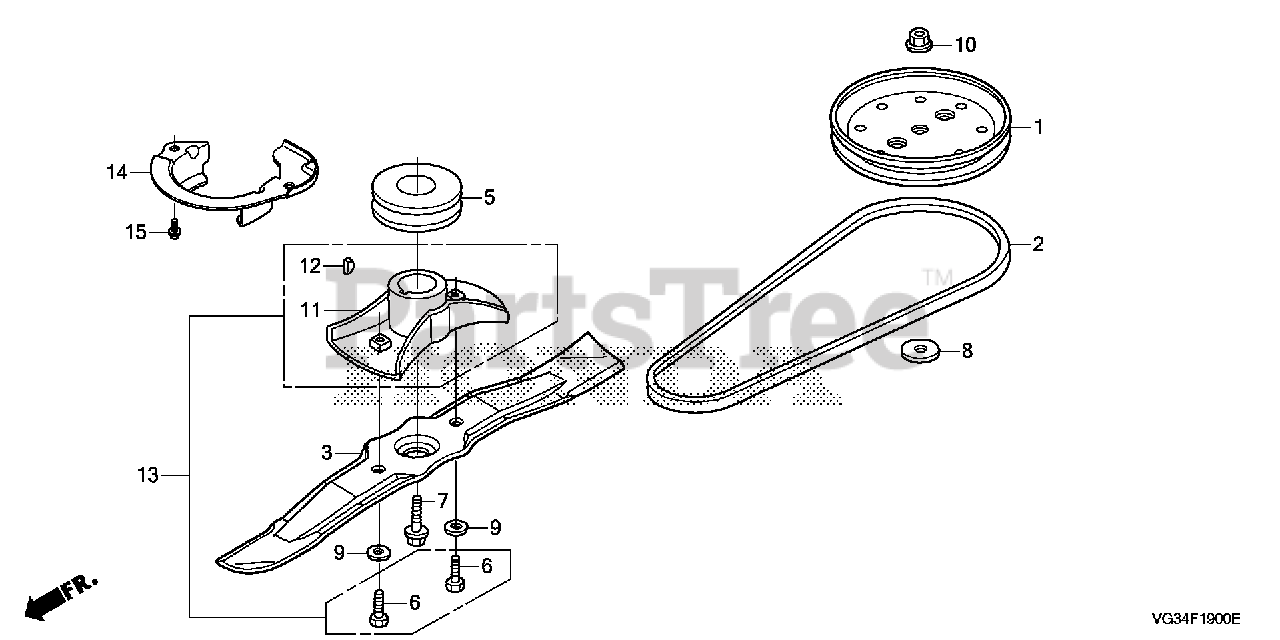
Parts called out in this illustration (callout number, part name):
2	V-BELT (3L-35)
3	BLADE, ROTARY
5	PULLEY, DRIVE
6	BOLT, HEX. (10X25)
7	BOLT, FLANGE (3/8-24X1")
9	WASHER, SPRING (10MM)
11	HOLDER, BLADE
12	KEY, WOODRUFF (3/16X5/8)
14	GUIDE, ENGINE BELT
15	BOLT, FLANGE (6X14) (CT200)
